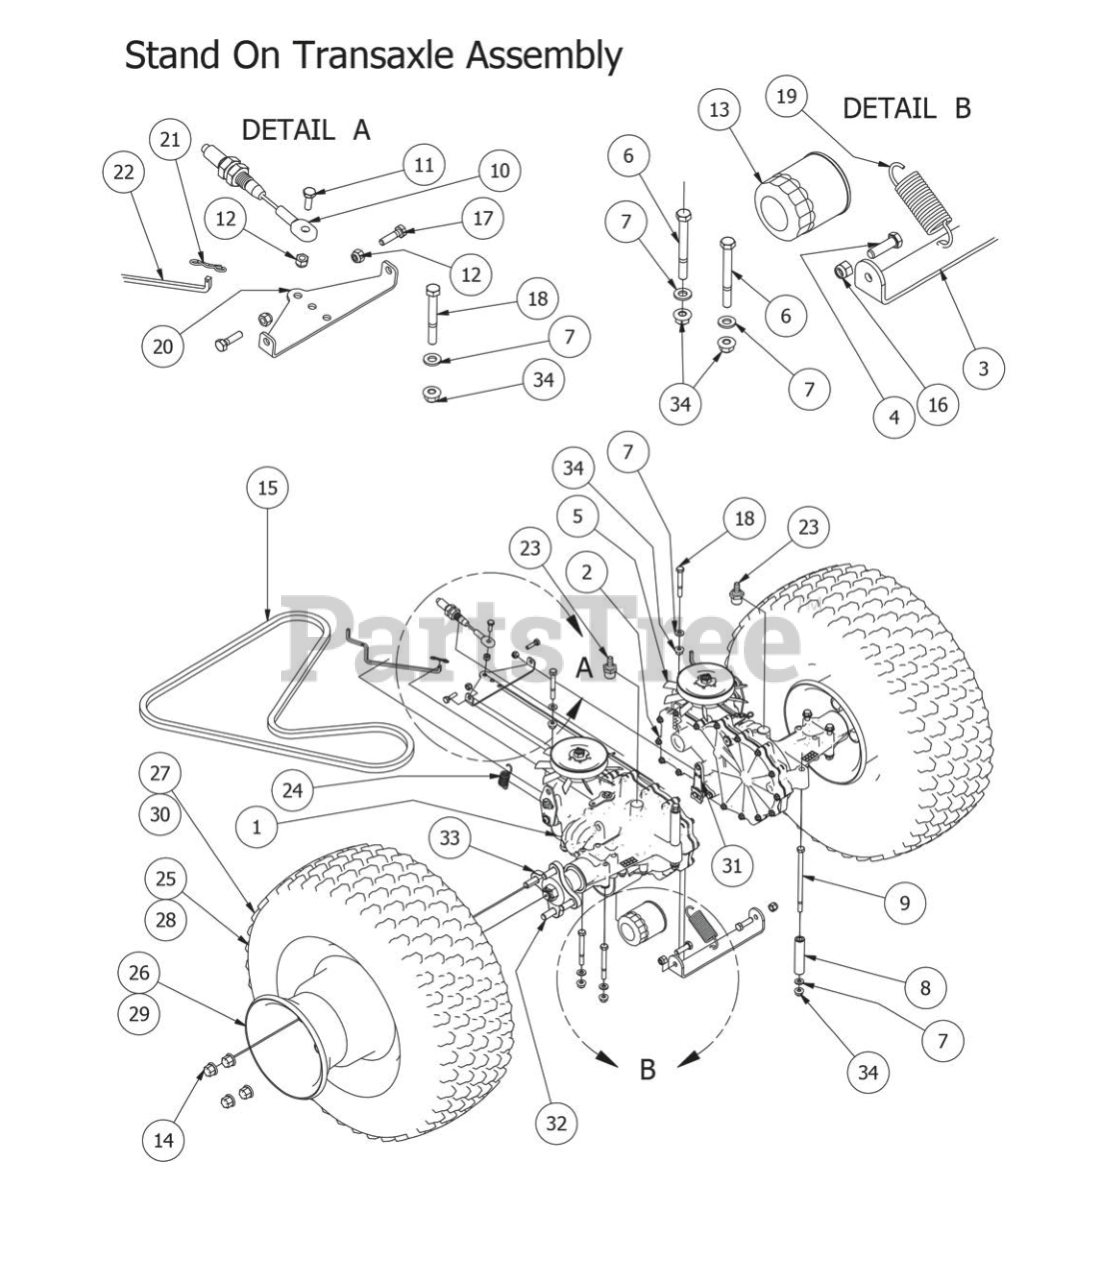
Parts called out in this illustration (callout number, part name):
1	Left 3400 IZT for CZT
2	Right 3400 IZT for CZT
3	Crossover Bar for ZT
4	3/8" x2" Hex Bolt
5	Fan/Pulley Kit For CZT
6	5/16" x 3" Hex Bolt
7	5/16" Flat Washer
8	3 1/4" Spacer
9	5/16" x 6" Bolt
10	Brake Cable
11	1/4" x 3/4" Hex Bolt
12	1/4" Nylock Nut
13	Transaxle Hydro Filter
14	Acorn Lug Nut
16	3/8 Nylock Nut
17	1/4-20 x 1 GR 5 hex bolt zinc
18	5/16" x 2 1/2" Bolt
20	Brake Bracket
22	MZ Brake Release Bar
23	45 degree fitting
24	Spring for Stand On Models
25	23 x 10.50 -12 Assembly W/Negative Offset Wheel
26	12 Orange Wheel
27	23 x 10.50-12 Tire
28	23 x 8.50 - 12 Tire & Wheel Assembly (48" Deck only)
29	23 x 8.50 (Wheel 48" Deck only)
30	23 x 8.50 -12 Tire (48" Deck only)
31	Transaxle Brake Lever
32	Transaxle Wheel Studs
33	ZT Transaxle Hub
34	5/16" Nylon Flange Nut
